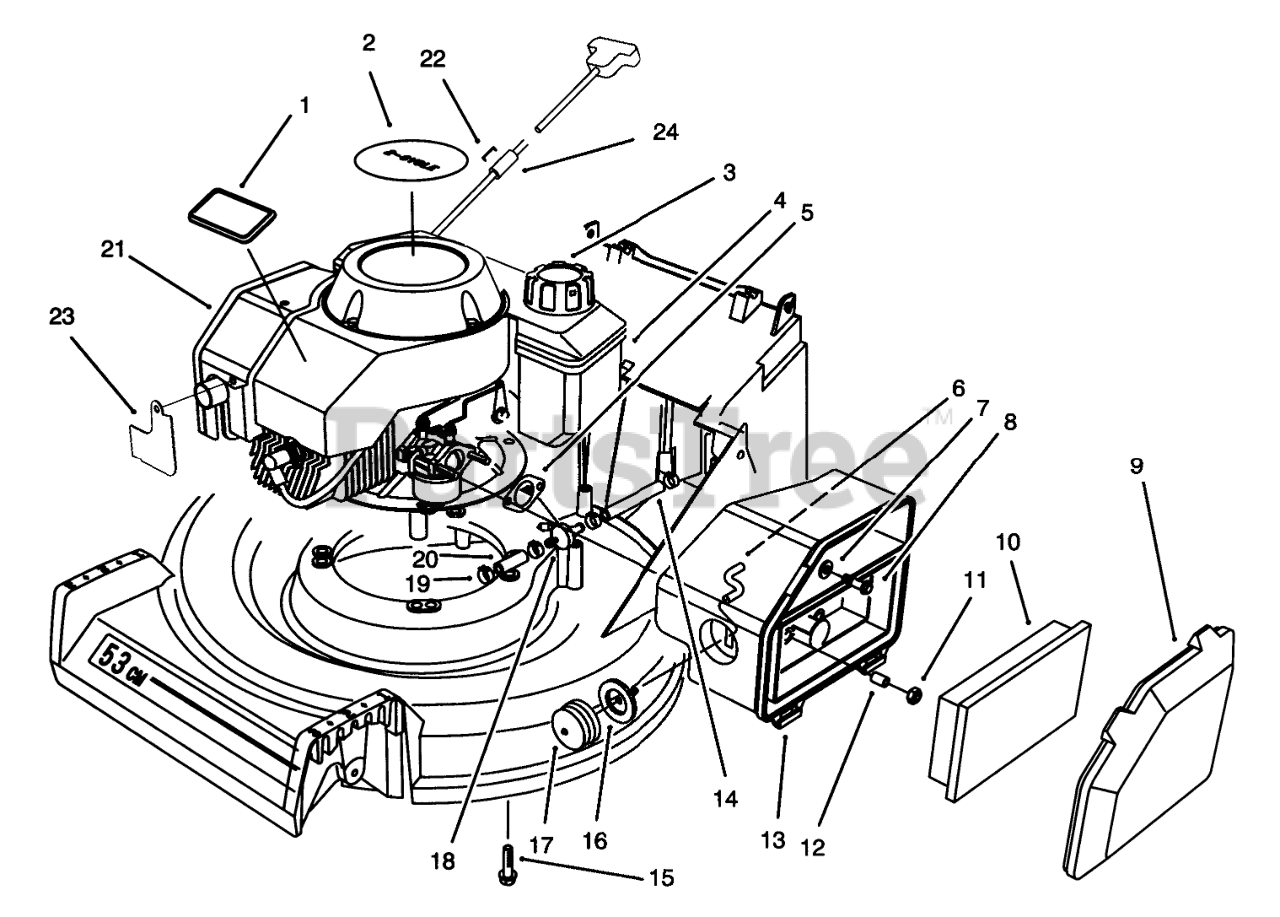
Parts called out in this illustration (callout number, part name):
1	TORO LOGO PLT
2	DECAL- 2 CYC RECOIL
3	GAS CAP ASM
4	FUEL TANK ASM
5	GASKET-AIR CLEANER
6	HOSE-PRIMER
7	WASHER-FLAT
8	SCREW-HH
9	COVER-AIR CLEANER
10	ELEMENT-AIR CLEANER
12	SPACER
13	Body-Air Cleaner
14	HOSE-FUEL
15	Bolt-Engine
16	BODY-PRIMER
17	BULB-PRIMER
18	FILTER-FUEL
19	CLAMP-FUEL LINE
20	HOSE-FUEL
21	ENGINE 121CC INT'L 2CYC
22	Staple
23	EXTENSION-MUFFLER GUARD
